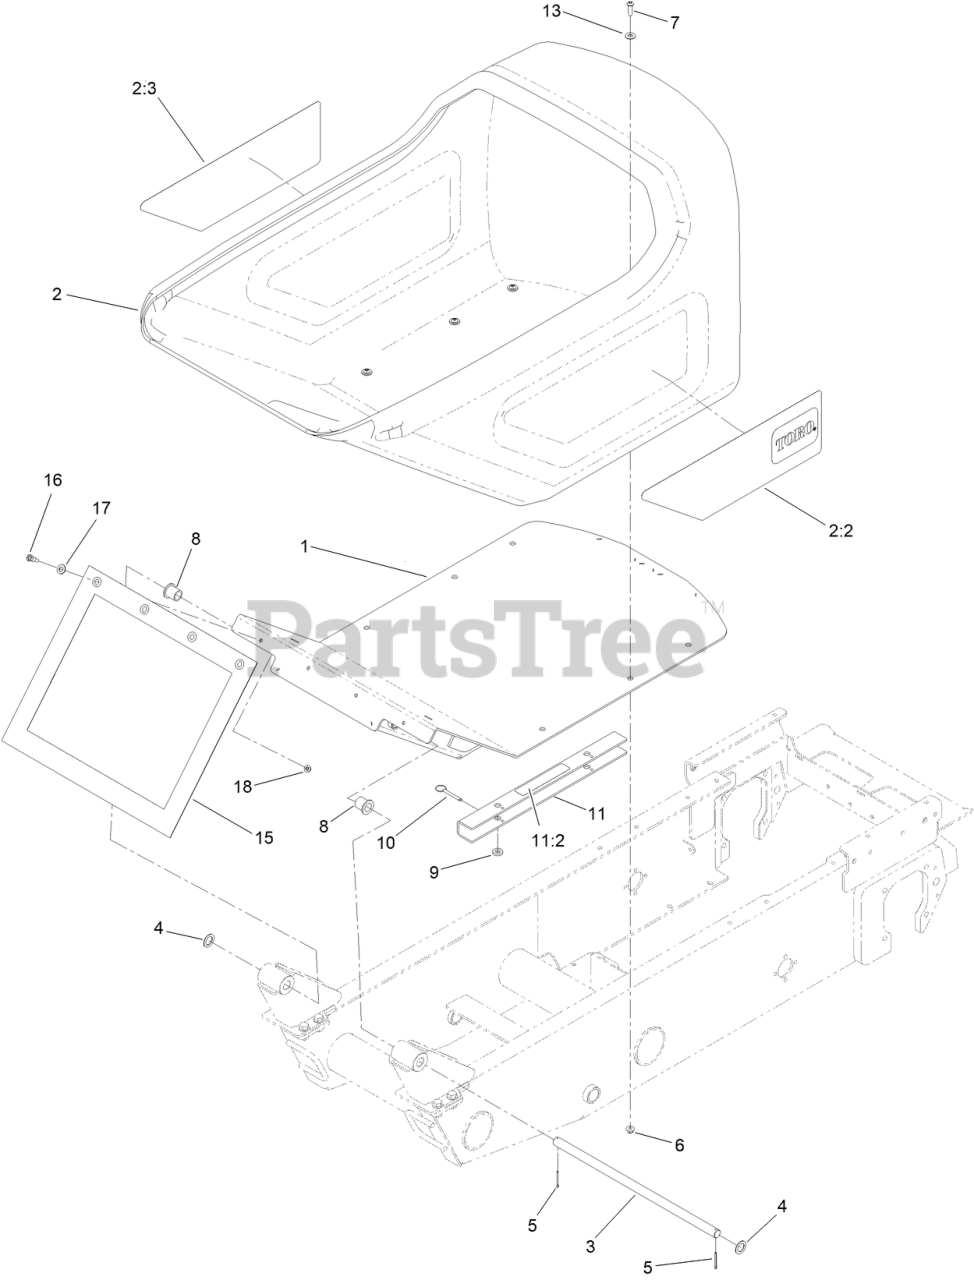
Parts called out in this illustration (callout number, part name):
1	FRAME-HOPPER ASM
2	HOPPER-MORTAR ASM
2:2	DECAL-TUB, LEFT
2:3	DECAL-TUB, RIGHT
3	SHAFT-PIVOT,TUB
4	SPACER
5	PIN-COTTER
6	NUT-HF, NI
7	SCREW-HSBH
8	BEARING-FLANGED
9	WASHER-NEOPRENE
10	PIN-COTTERLESS
11	ARM-LOCKING
11:2	DECAL-DANGER
13	WASHER-FLAT
15	SHIELD-SPLATTER
16	BOLT-SHOULDER
17	WASHER-FLAT
18	NUT-HF, NI
